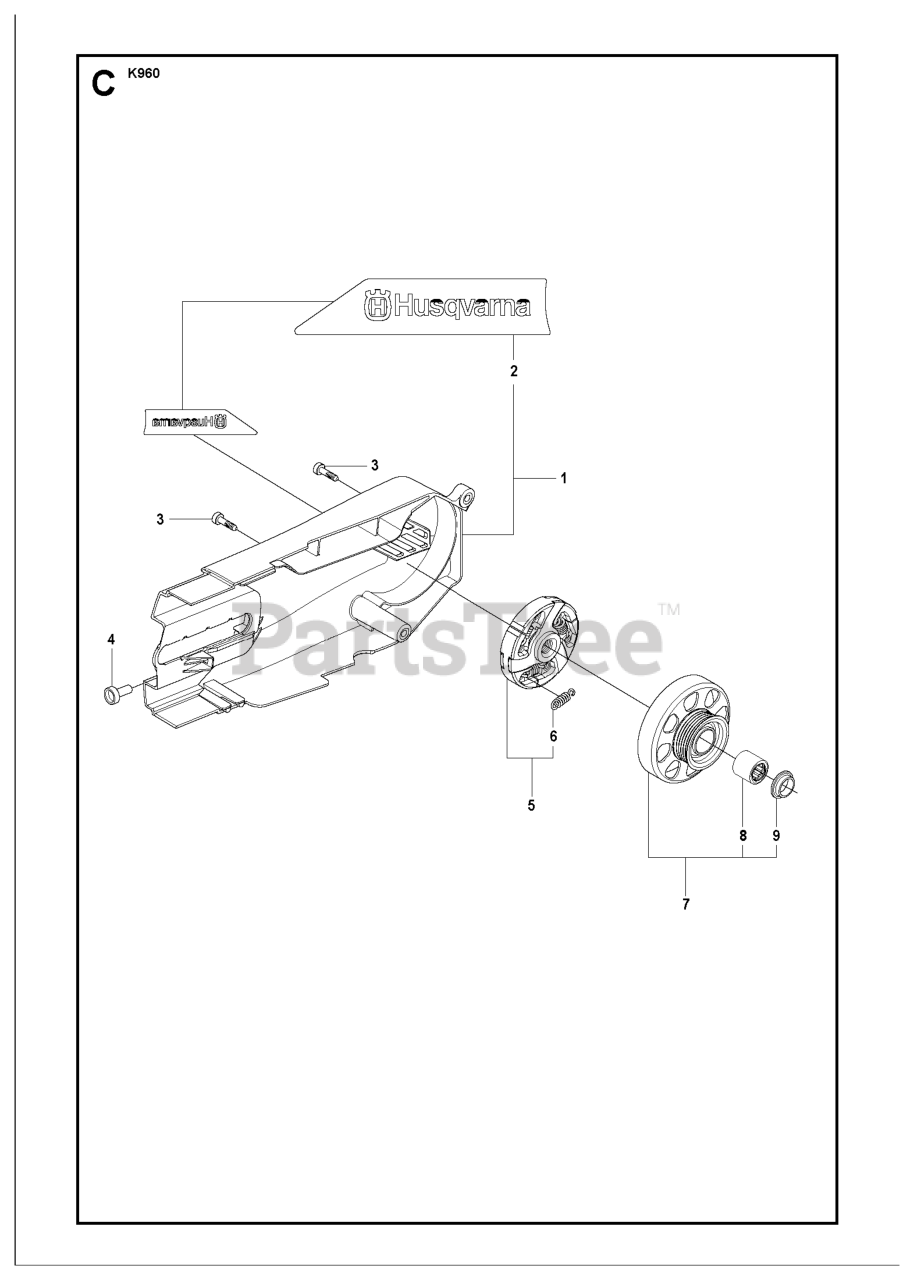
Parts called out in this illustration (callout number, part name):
1	BELT GUARD
2	LABEL BELT GUARD
4	LINING
5	CLUTCH COMPLETE
6	CLUTCH SPRING
7	DRIVING PULLEY ASSY
7	WHEEL
8	SUPPORT BUSHING
